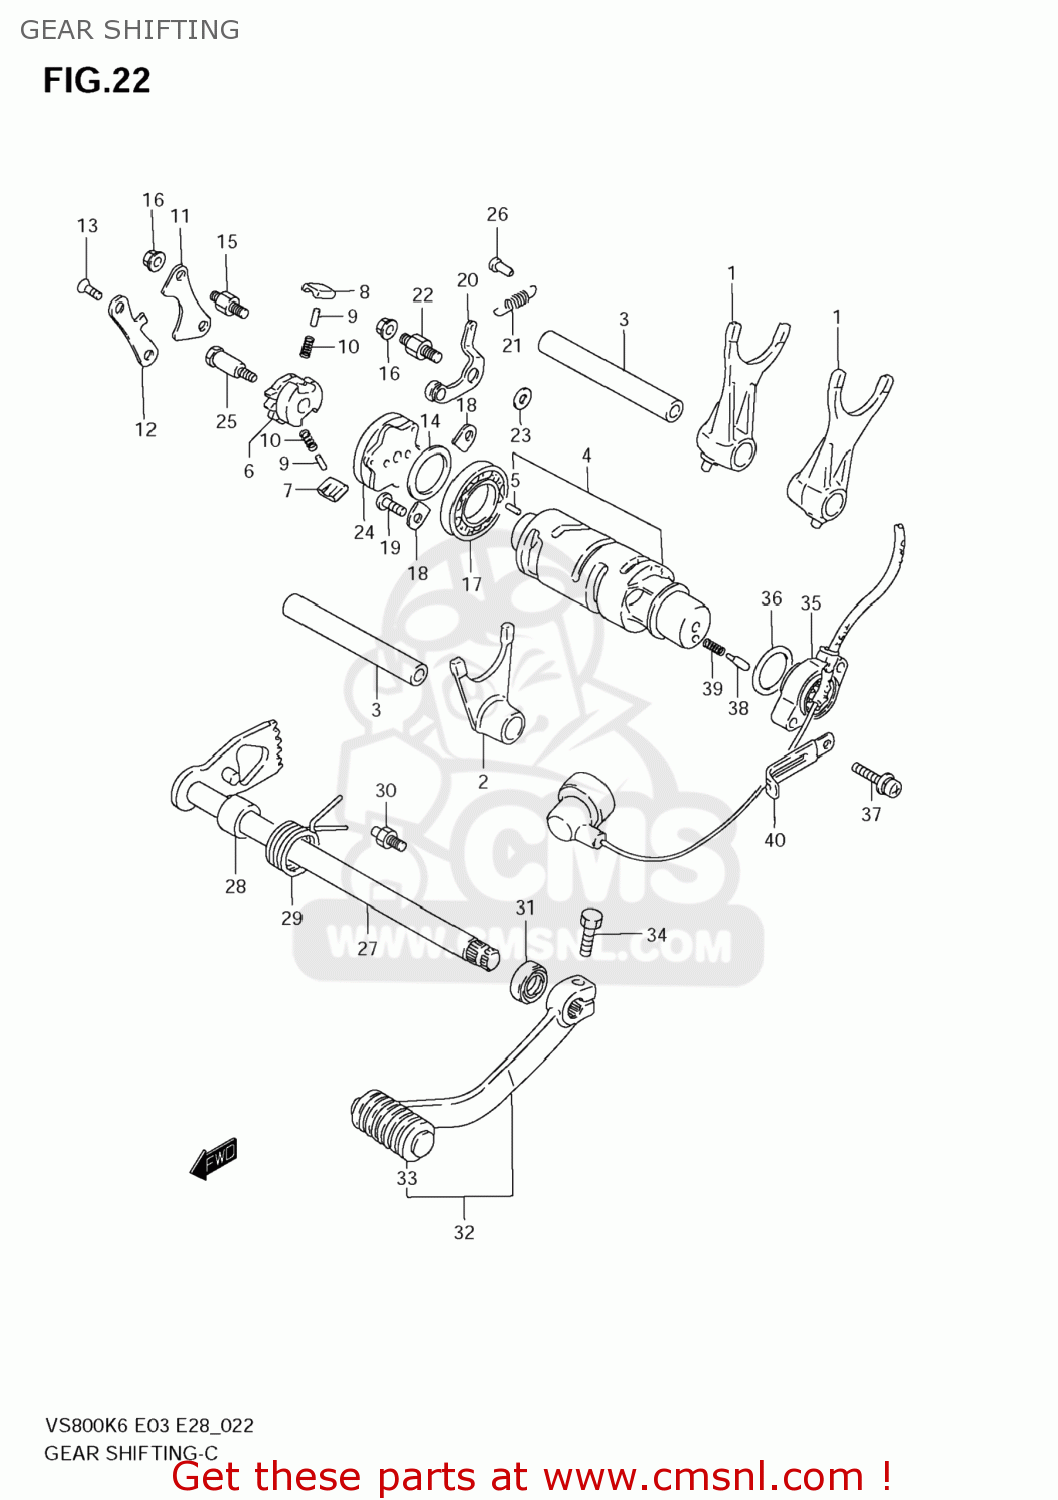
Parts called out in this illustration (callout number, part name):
1	FORK,GEAR SHIFT NO.1
2	FORK,GEAR SHIFT NO.2
3	SHAFT,GEAR SHIFT FORK(L:115)
4	CAM,GEAR SHIFT
5	PIN
6	GEAR,GEAR SHIFT CAM DRIVEN
7	PAWL,GEAR SHIFT NO.1
8	PAWL,GEAR SHIFT NO.2
9	PIN(5X8)
10	SPRING
11	LIFTER,GEAR SHIFT POLE
12	GUIDE,GEAR SHIFT CAM
13	SCREW(6X12)
14	WASHER(25X32X3)
15	BOSS,SHIFT POLE LIFTER
16	NUT
17	BEARING(25X47X8)
18	RETAINER
19	BOLT(6X12)
20	STOPPER,GEAR SHIFT CAM
21	SPRING
22	SUPPORT,CAM STOPPER ARM
23	WASHER
24	PLATE,GEAR SHIFT CAM
25	PIN,SHIFT CAM DRIVEN GEAR
26	RIVET
27	SHAFT,GEAR SHIFT
28	SPACER(12X20X15.3)
29	SPRING
30	STOPPER,GEAR SHIFT ARM
31	OIL SEAL
32	LEVER ASSY,GEAR SHIFT
33	RUBBER,GEAR SHIFT PEDAL
34	BOLT
35	BASE,NEUTRAL SWH TERMINAL
36	O RING(D:2.4,ID:26.2)
37	SCREW
38	PIN(5X15.5)
39	SPRING
40	CLAMP(L:45)
